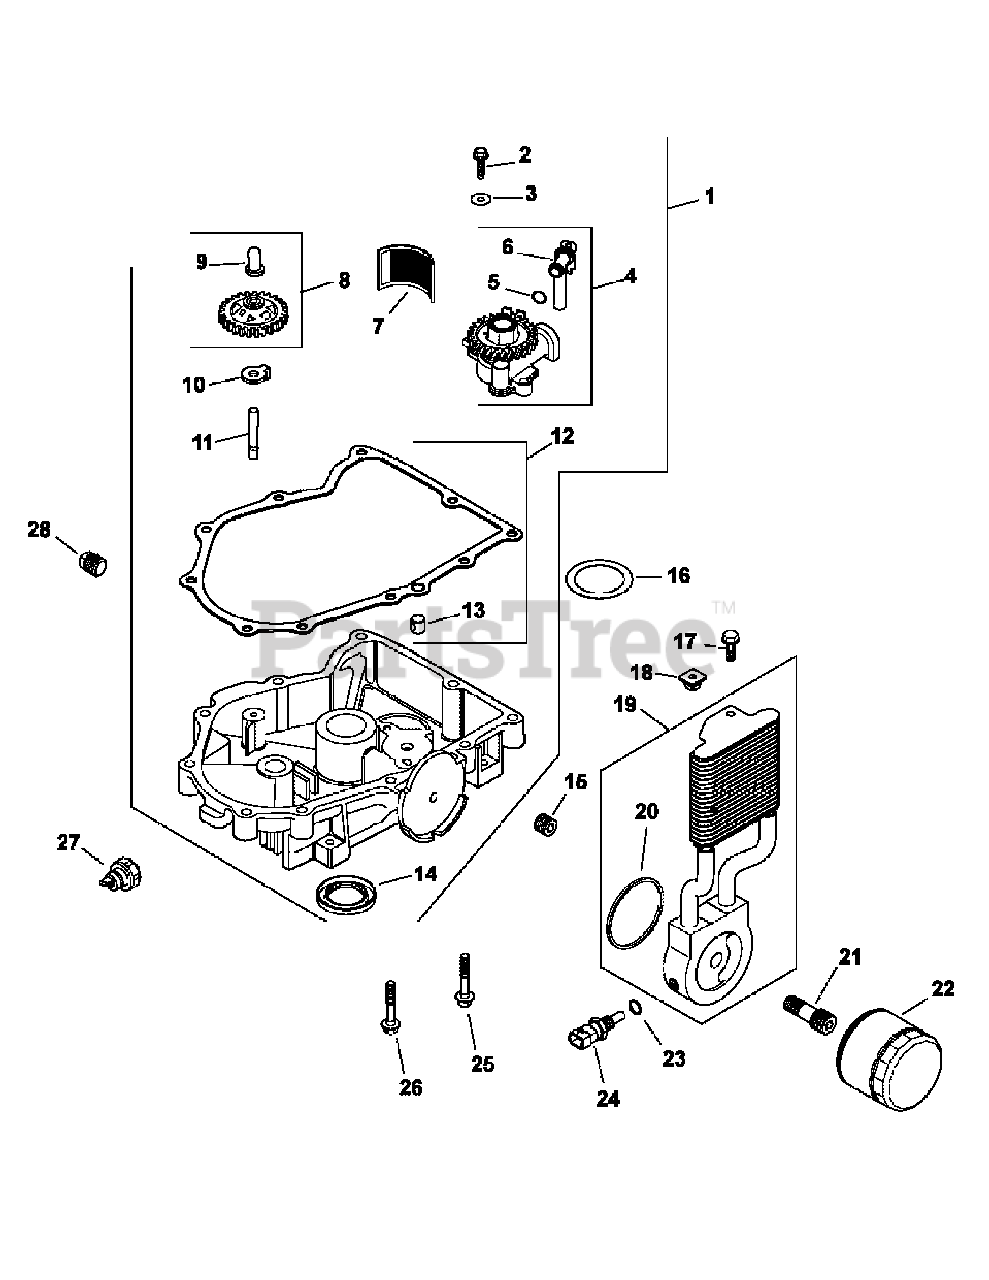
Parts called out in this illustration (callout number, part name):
1	Oil Pan Kit w/Gasket
2	Hex Flange Screw
3	Plain Washer
4	Oil Pump Assembly
5	Oil Pickup Tube O-Ring
6	Oil Pickup Tube
8	Governor Gear Kit
9	Governor Regulating Pin
11	Governor Gear Shaft
12	Oil Pan Gasket
14	Oil Seal (PTO End)
17	Hex Cap Screw
21	Oil Filter Nipple
24	Temperature Sensor
25	Hex Flange Screw
26	Hex Flange Screw
27	Oil Pressure Switch
28	Pipe Plug 3/8
